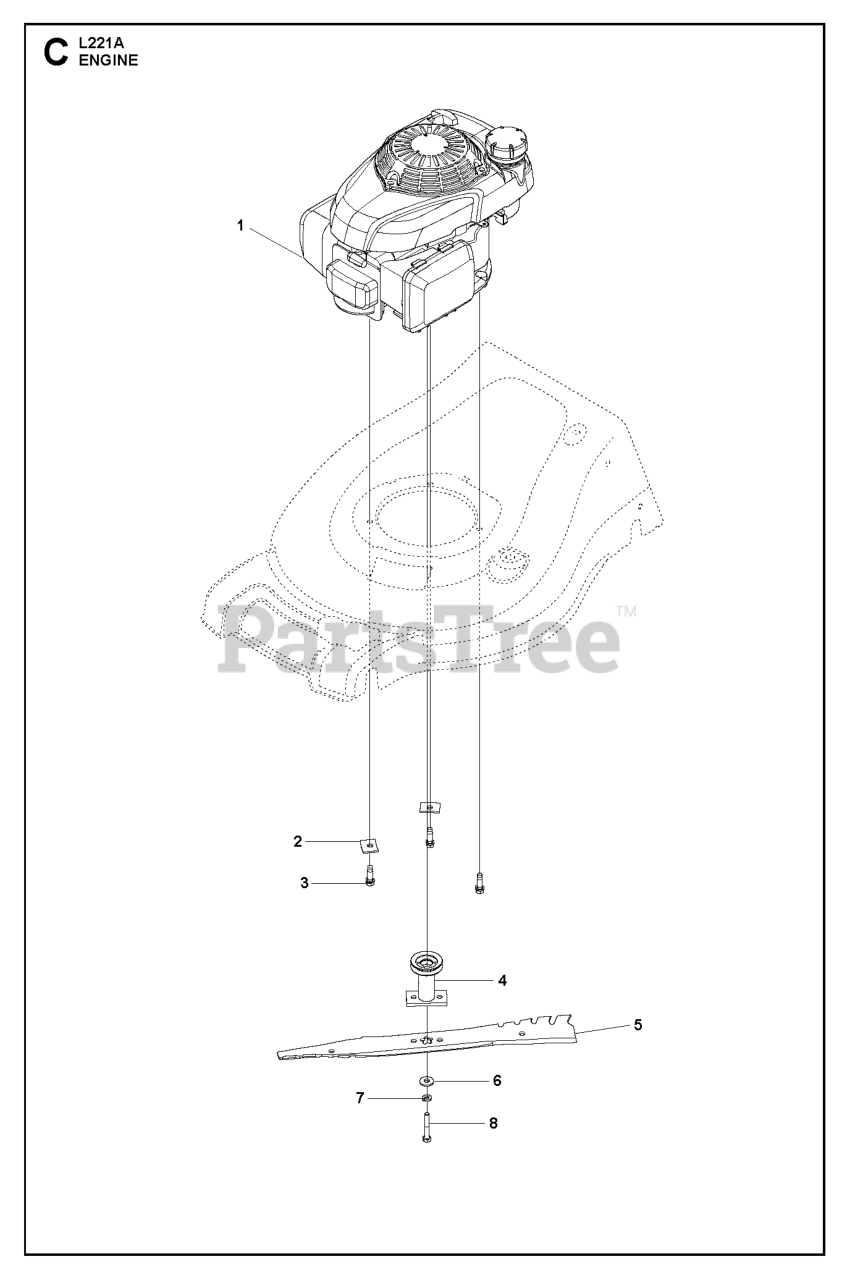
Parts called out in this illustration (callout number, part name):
2	WASHER.ENGINE.BZP
3	BOLT 3/8-16X1-1/8
4	ADAPTER.BLD.25M.2P.AW/RW/21EFF
5	BLADE.21.REAPER.WO/NOTCHES
6	WASHER,HARDEN
7	LOCKWASHER
8	BOLT.ENGINE.PULLEY
